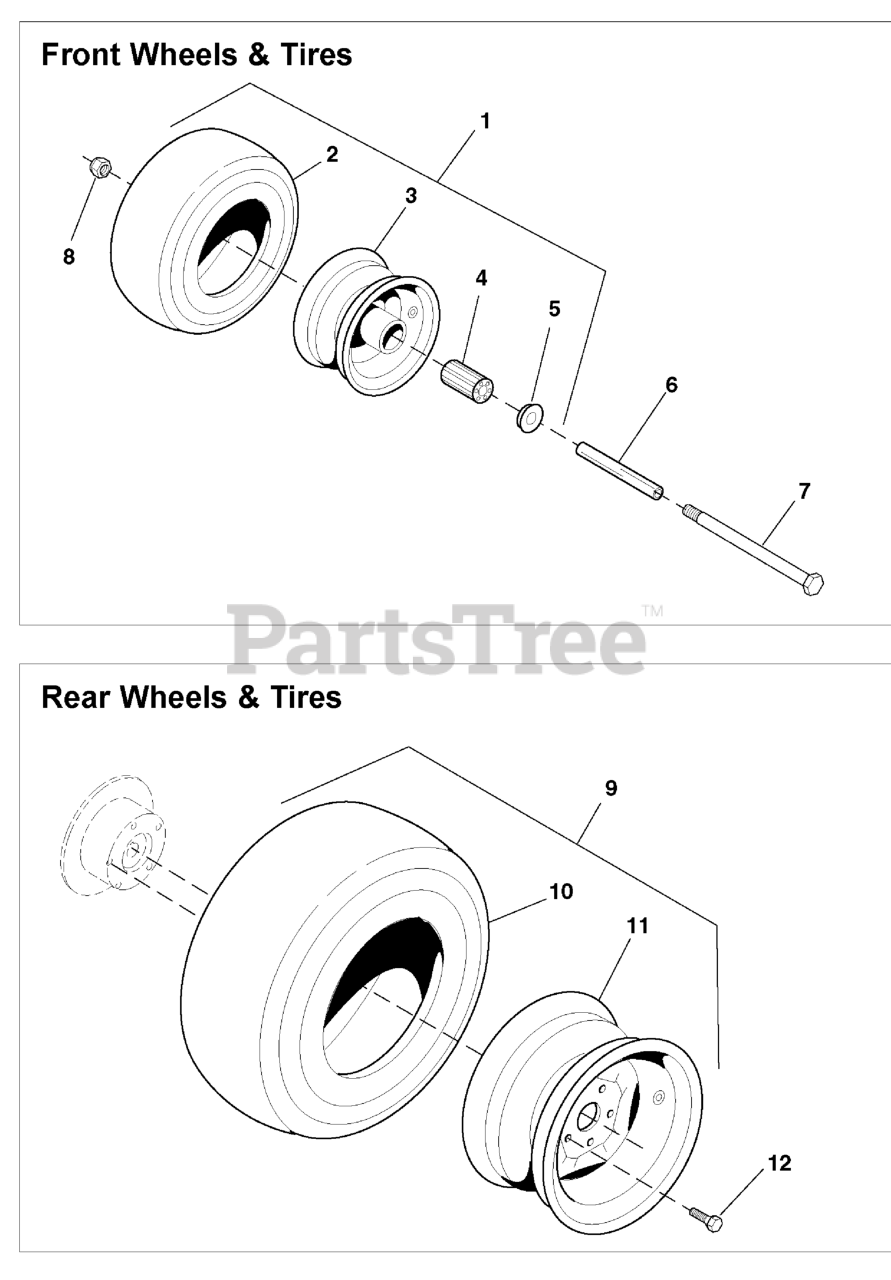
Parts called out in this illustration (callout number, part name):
1	WHEEL & TIRE ASSEMBLY, 13 x 5.0 x 6, Complete
2	TIRE, Front, 13 x 5.0 x 6
3	WHEEL ASSEMBLY, for 13 x 5.0 x 6 Tires, Complete
4	BEARING, Roller
5	RETAINER, Bearing
6	SHAFT, Caster Axle
7	BOLT, 1/2-13 x 7-1/2
8	NUT, 1/2-13 HEX NYLON LOCK
9	WHEEL & TIRE ASSEMBLY, 23 x 10.5 x 12, Complete
9	WHEEL & TIRE ASSEMBLY, 23 x 8.5 x 12, Complete
10	TIRE, Rear, 23 x 10.5 x 12
10	TIRE, Rear, 23 x 8.5 x 12
11	WHEEL ASSEMBLY, for 23 x 10.5 x 12 Tires
11	WHEEL ASSEMBLY, for 23 x 8.5 x 12 Tires
12	WHEEL LUG, 1/2 x 1-5/8
